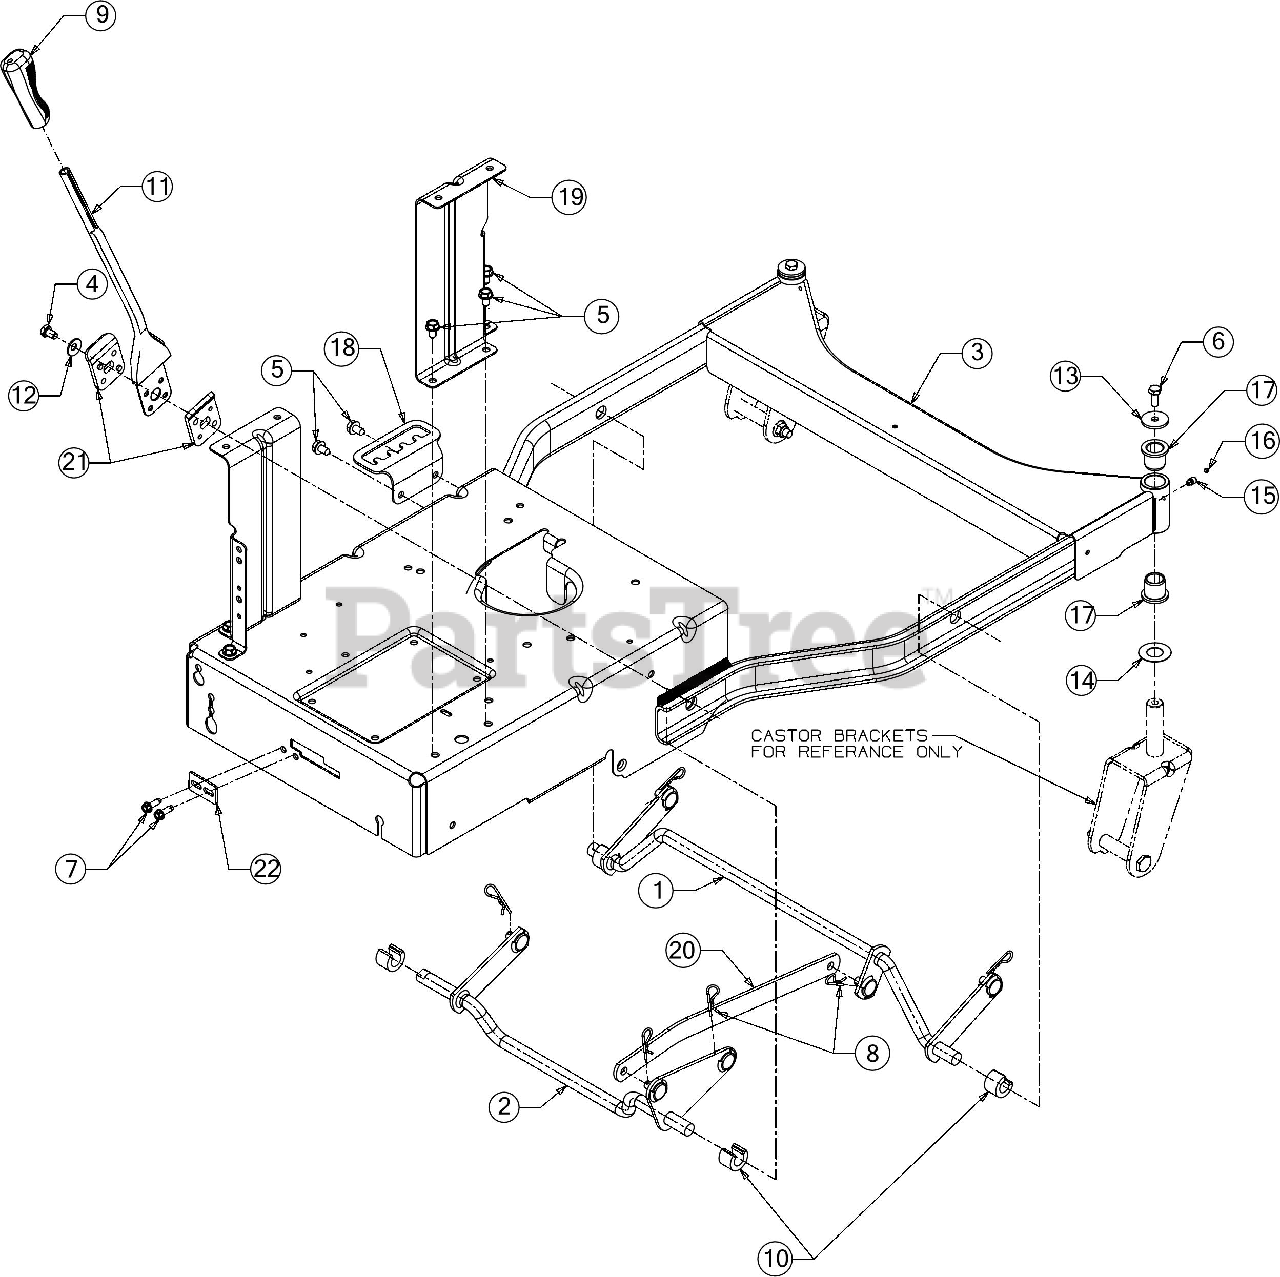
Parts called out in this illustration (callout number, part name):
1	FRONT LIFT ASSEMBLY
2	DECK LIFT ASSEMBLY
3	FRAME ASSEMBLY
3	FRAME BRACKET
4	SCREW 5/16-18 X .50
5	SCREW 5/16-18 X .625
6	SCREW 5/16-24 X .750 GR5
7	SCREW 1/4-20 X .750
8	INTERNAL COTTER PIN
9	HANDLE GRIP
10	SNAP SPACER
11	DECK HEIGHT LEVER
12	BELL WASHER .337 X.867 X .057
13	WASHER-5/16 X 1.25X 1.27
14	THRUST WASHER
15	GREASE FITTING
16	GREASE
17	FLANGE BEARING .760 ID
18	HEIGHT ADJUSTMENT BRACKET
19	FUEL TANK BRACKET
21	HEIGHT LEVER BRACKET
22	SHIFT PLATE
